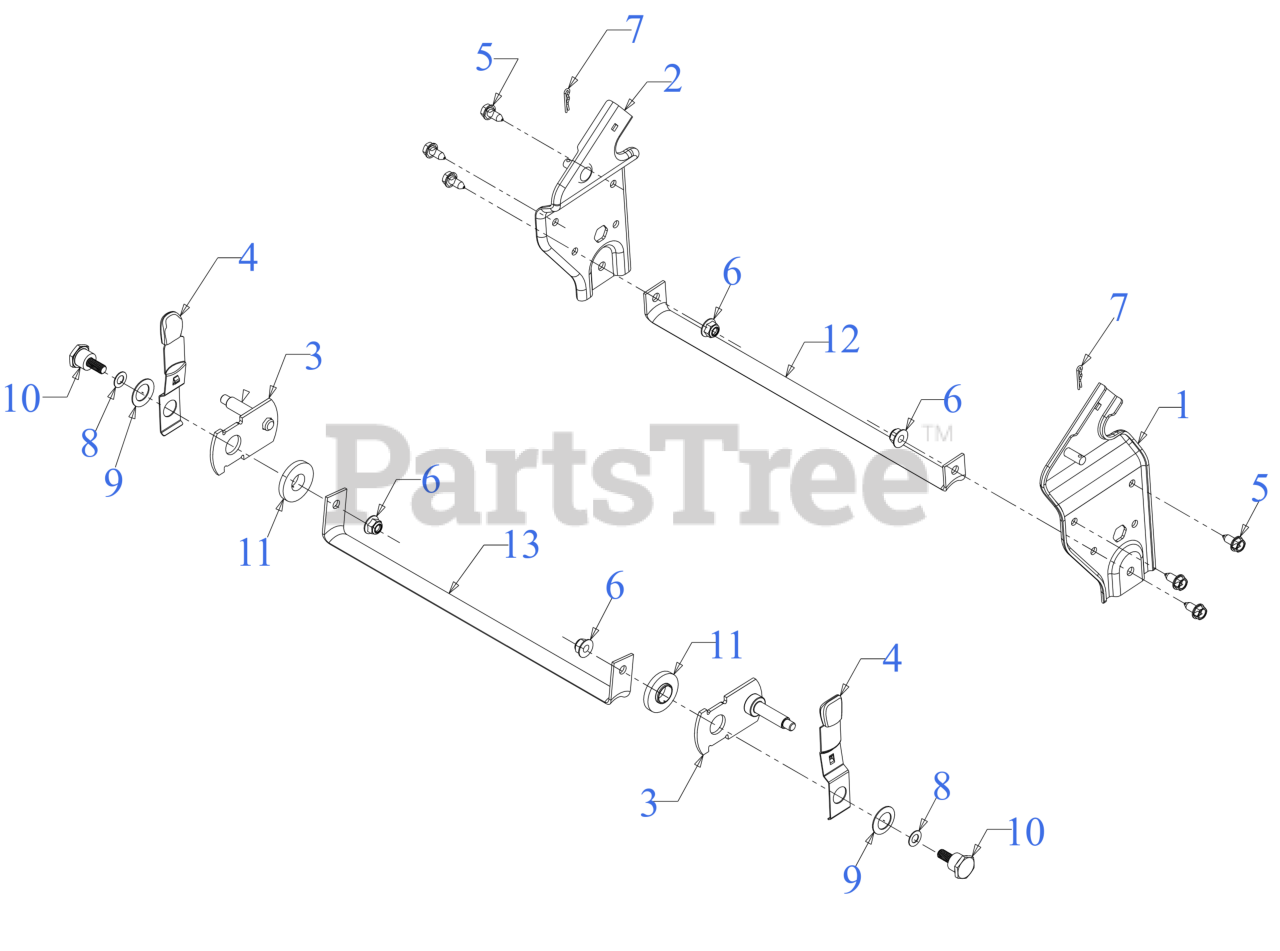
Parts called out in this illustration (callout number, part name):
3	PIVOT ARM ASSEMBLY
4	HEIGHT LEVER ASSEMBLY
5	SCREW 5/16-12 x .750
7	COTTER PIN .072 DIA
8	WASHER THRUST .375X.70X.030
9	BELL WASHER
10	SHOULDER SCREW .75 X.50 X3/8-16
11	HEIGHT ADJUSTMENT BEARING
12	SUPPORT BRACE
13	SUPPORT BRACE
